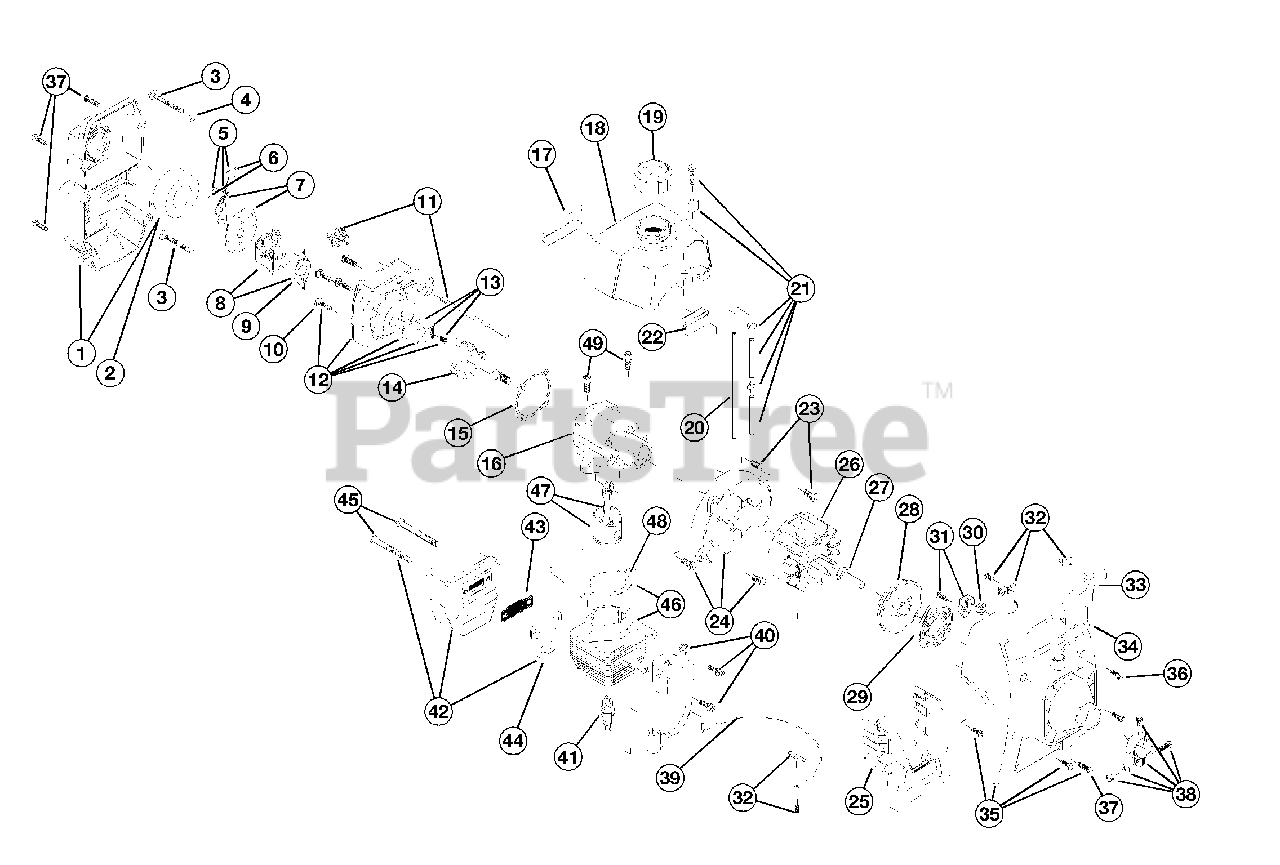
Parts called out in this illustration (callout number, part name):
1	Air Cleaner/Muffler Cover Assembly
2	Air Cleaner Filter
3	Carburetor Mounting Screw Assembly
4	Wavey Washer
5	Choke Lever Assembly
6	Choke Knob and Screw
7	Choke Lever and Plate
8	Carburetor Assembly
9	Carburetor Gasket
10	Carb Mount Screw
11	Primer and Hose Assembly
12	Carb Mount Assembly
13	Reed Assembly
14	Power Shaft Assembly
15	Crank Case Gasket
16	Crank Case Service Assembly
17	Rear Mounting Pad
18	Fuel Tank Assembly
19	Fuel Cap Assembly
20	Fuel Return Line
21	Fuel Line Assembly
22	Front Mounting Pad
23	Shroud Assembly
24	Shroud Screw
25	Shroud Extension & Stand
26	Flywheel Assembly
27	Square Nut Drive
28	Recoil Pulley Assembly
29	Recoil Spring
30	Rope Guide
31	Pulley Retainer Assembly
32	Switch Assembly
33	Pull Handle
35	Starter Housing Assembly
36	Housing Screw
37	Cover Screw
38	Upper Clamp Assembly
39	Wire Lead
40	Module Assembly
41	Spark Plug
42	Muffler Assembly
43	Spark Arrestor
44	Exhaust Gasket
45	Muffler Mounting Bolt Assembly
46	Cylinder Assembly
47	Piston and Rod Assembly
48	Cylinder Gasket
49	Cylinder Bolt
